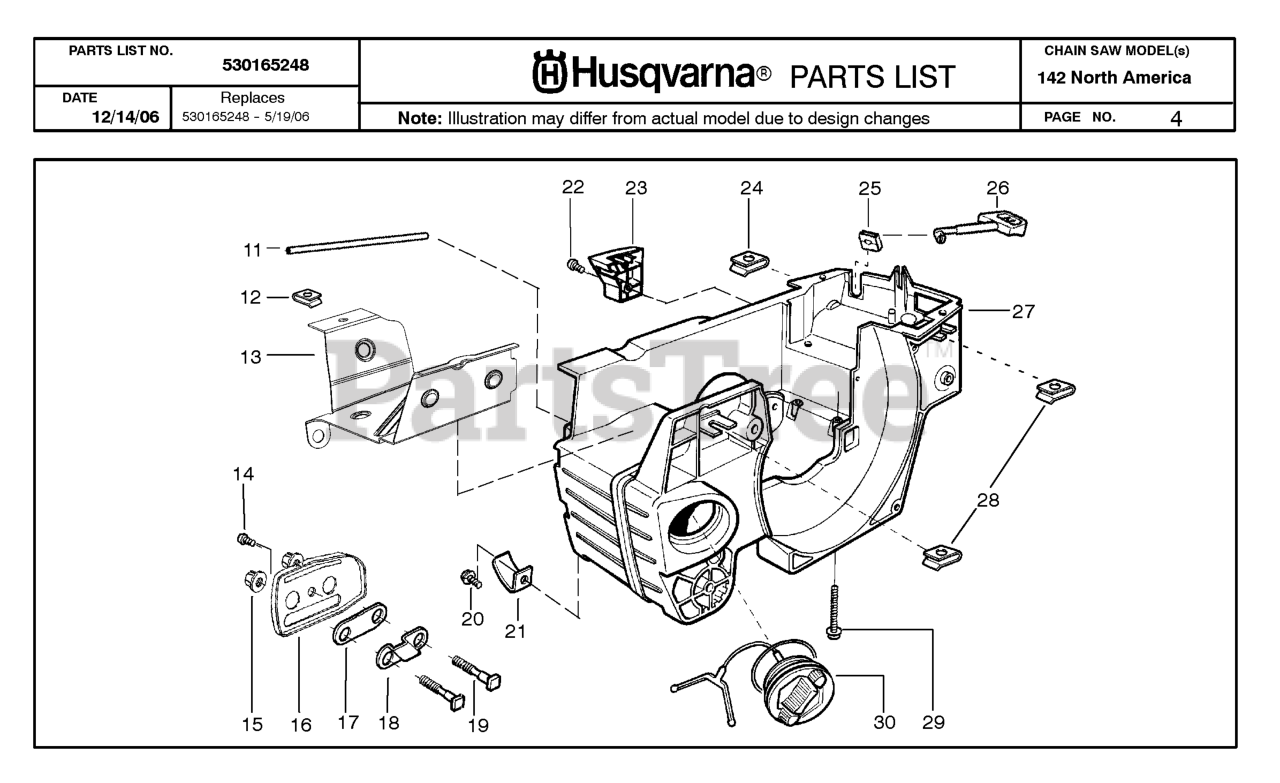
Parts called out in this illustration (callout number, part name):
13	HEATSHIELD, LOWER
17	OIL TANK GASKET
18	PLATE,BAR MOUNT
19	BAR BOLT 36/41
21	CHAIN CATCHER 36/41
23	LIMITER COVER
25	CHOKE GUIDE 36/41
26	CHOKE 36/41
27	KIT ASSY CHASSIS
29	SCREW M5-0.8X35M TAP
